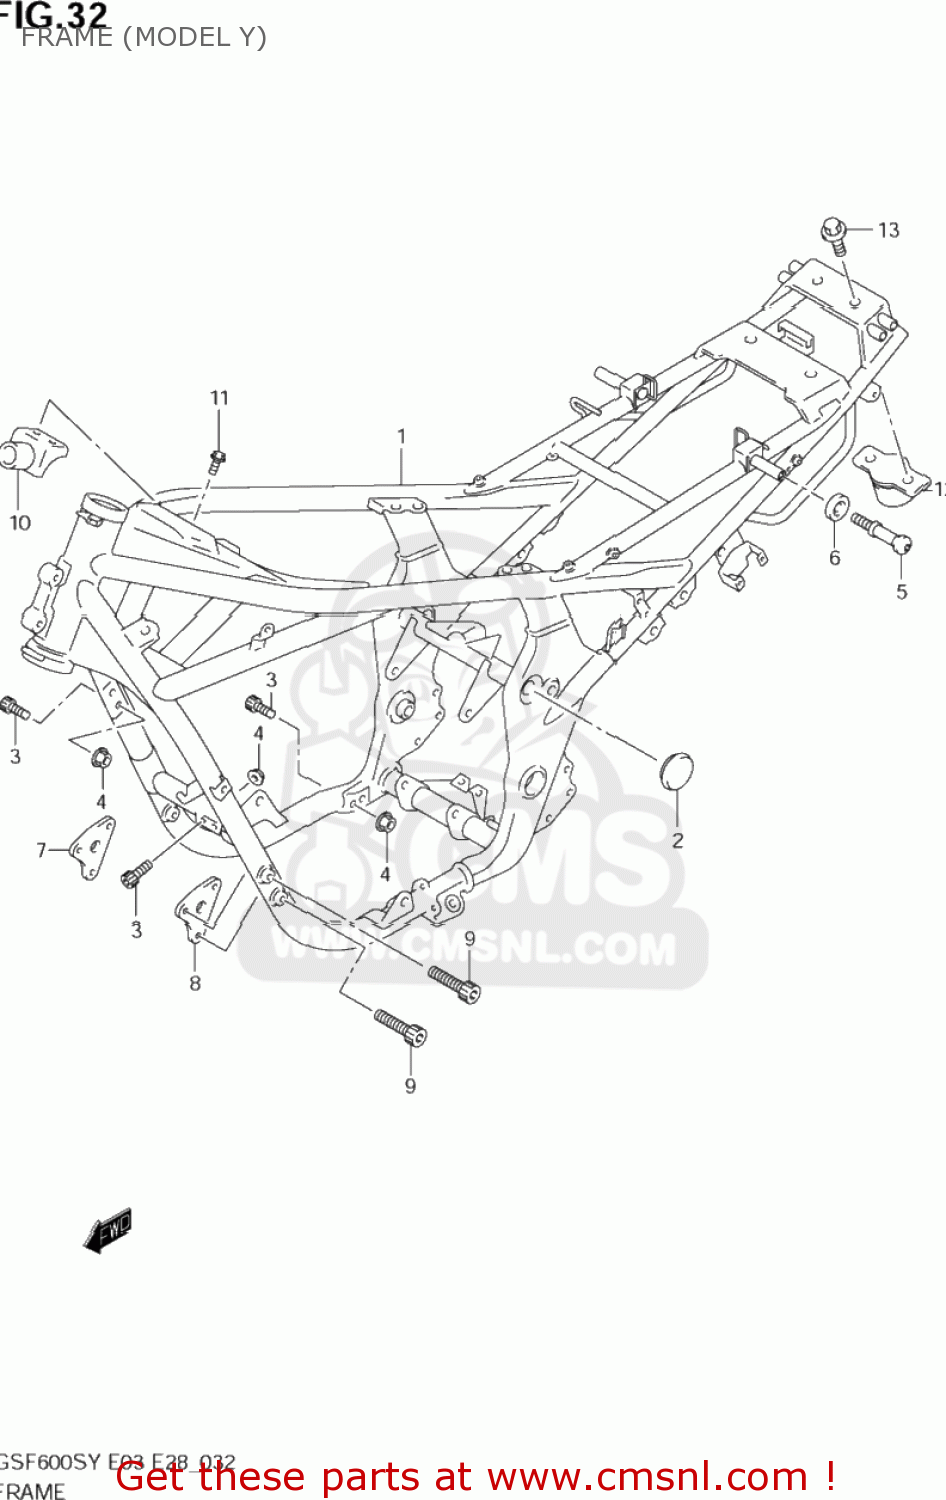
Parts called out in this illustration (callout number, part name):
1	FRAME(RED)
2	CAP,FRAME BODY
3	BOLT(10X37)
4	NUT
5	HOOK,SEAT RAIL
6	WASHER,HOOK
7	PLATE,ENG MTG,R
8	PLATE,ENG MTG,L
9	BOLT
10	DAMPER,FRAME
11	BOLT
12	DAMPER,FRAME RR
13	BOLT
